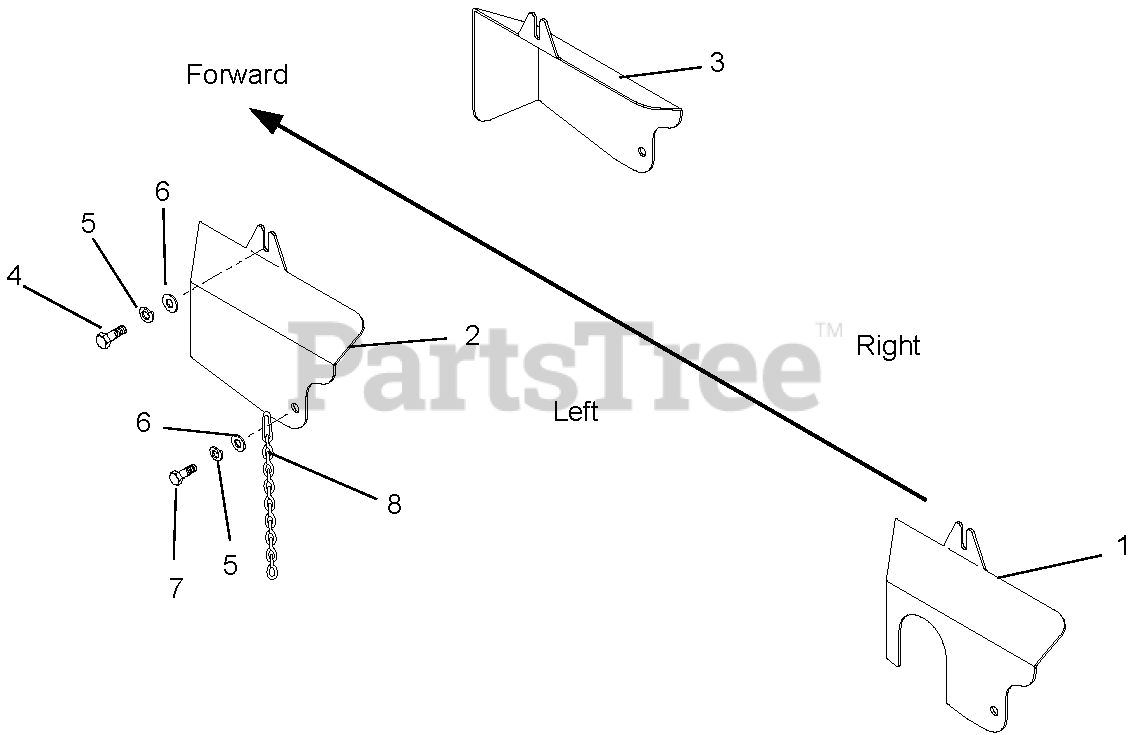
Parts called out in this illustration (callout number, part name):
1	Weldment, Belt Guard Center Rear (Unit #1)
2	Weldment, Belt Guard Outside Left (Unit #2 TVM)
3	Weldment, Belt Guard Outside Right (Unit #3 TVM)
4	Cap Screw, Hex Head .312 x .75
5	Washer, Lock .312
6	Washer, Flat .312
7	Cap Screw .312-18 x 1.25
8	Chain, Safety
